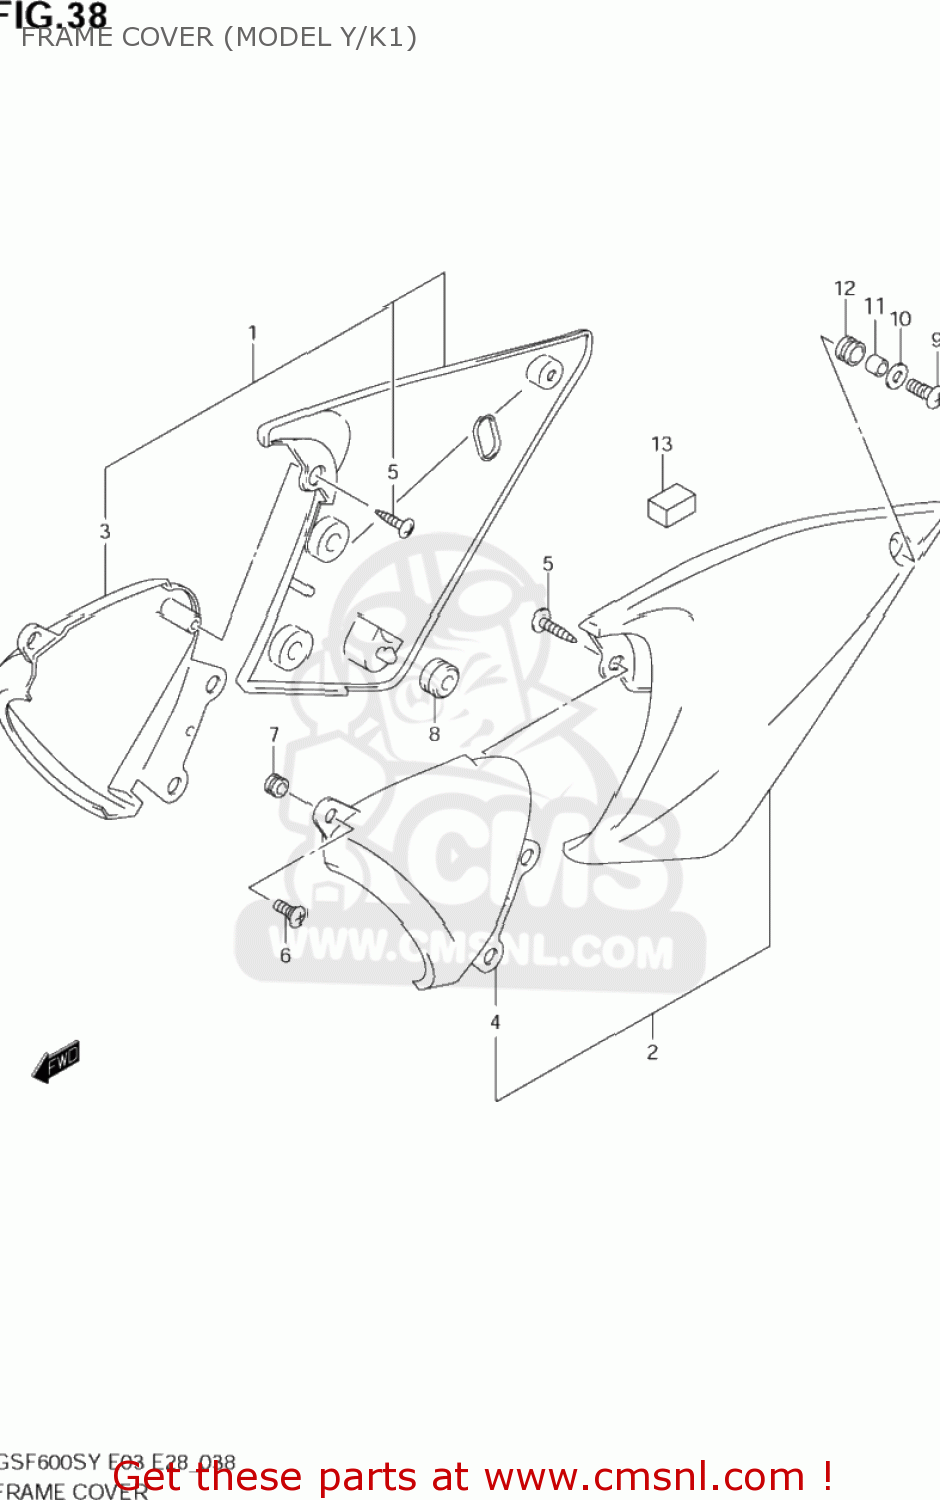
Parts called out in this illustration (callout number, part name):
1	COVER,FRAME,R(GRAY)
2	COVER,FRAME,L(GRAY)
3	COVER,FRAME FR,R
4	COVER,FRAME FR,L
5	SCREW
6	SCREW,FRAME COVER,FRONT
7	CUSHION,FRAME COVER FR
8	CUSHION
9	SCREW(6X16)
10	WASHER(6.5X18X1)
11	SPACER(6.5X9X9)
12	CUSHION
13	PAD,HEAD COVER CAP
